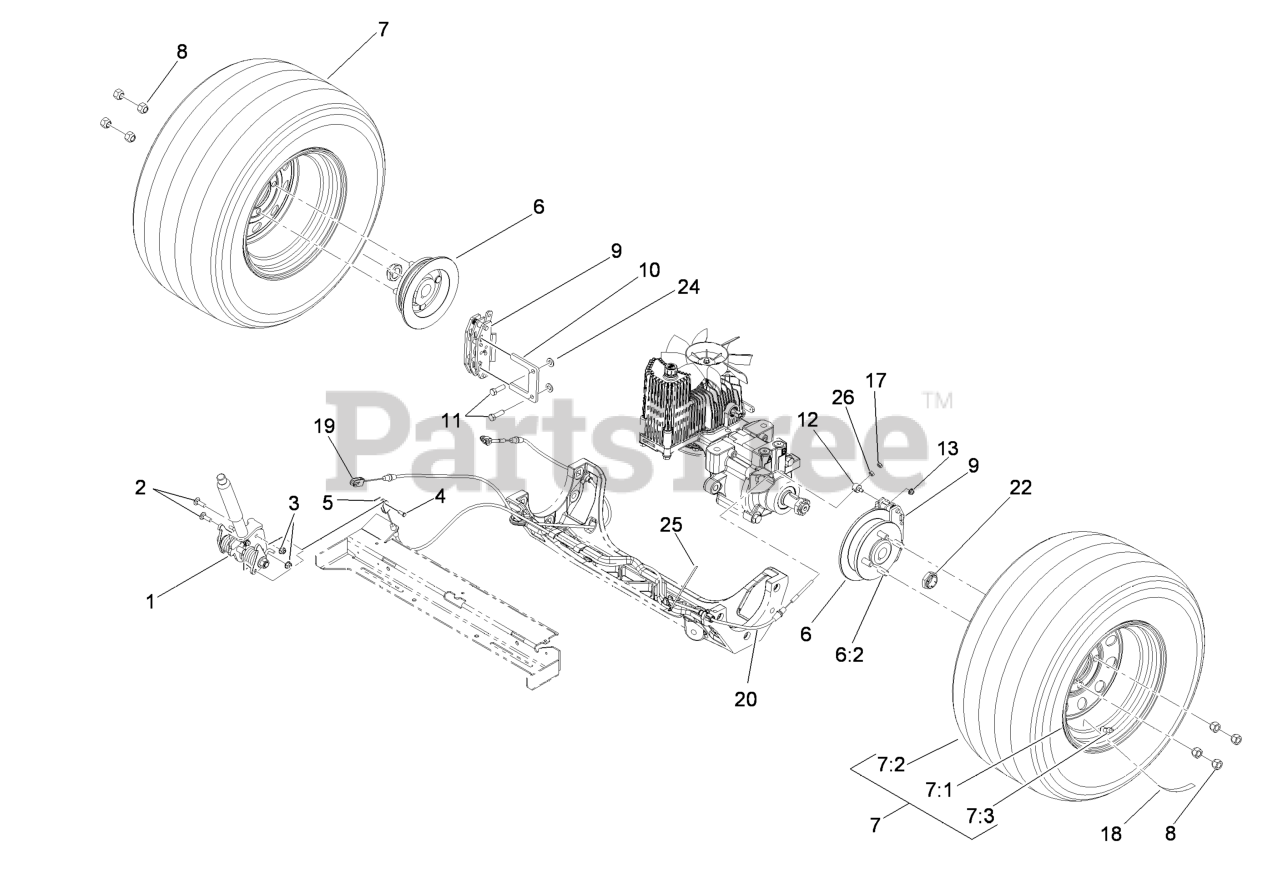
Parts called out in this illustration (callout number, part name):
1	BRAKE HANDLE ASM
2	BOLT-CARR
3	NUT-HF, NI
4	PIN-CLEVIS
5	PIN-COTTER
6	WHEEL HUB ASM
6:2	STUD-WHEEL
7	WHEEL AND TIRE ASM
7:1	RIM ASM
7:2	TIRE
7:3	Stem-Valve
8	NUT-LUG
9	CALIPER-BRAKE
10	PLATE-MOUNT, BRAKE
11	SCREW-LOCK, PATCH
17	NUT-LOCK, NI
22	LOCKNUT
24	WASHER-FLAT
25	TIE-CABLE
26	NUT-HEX
